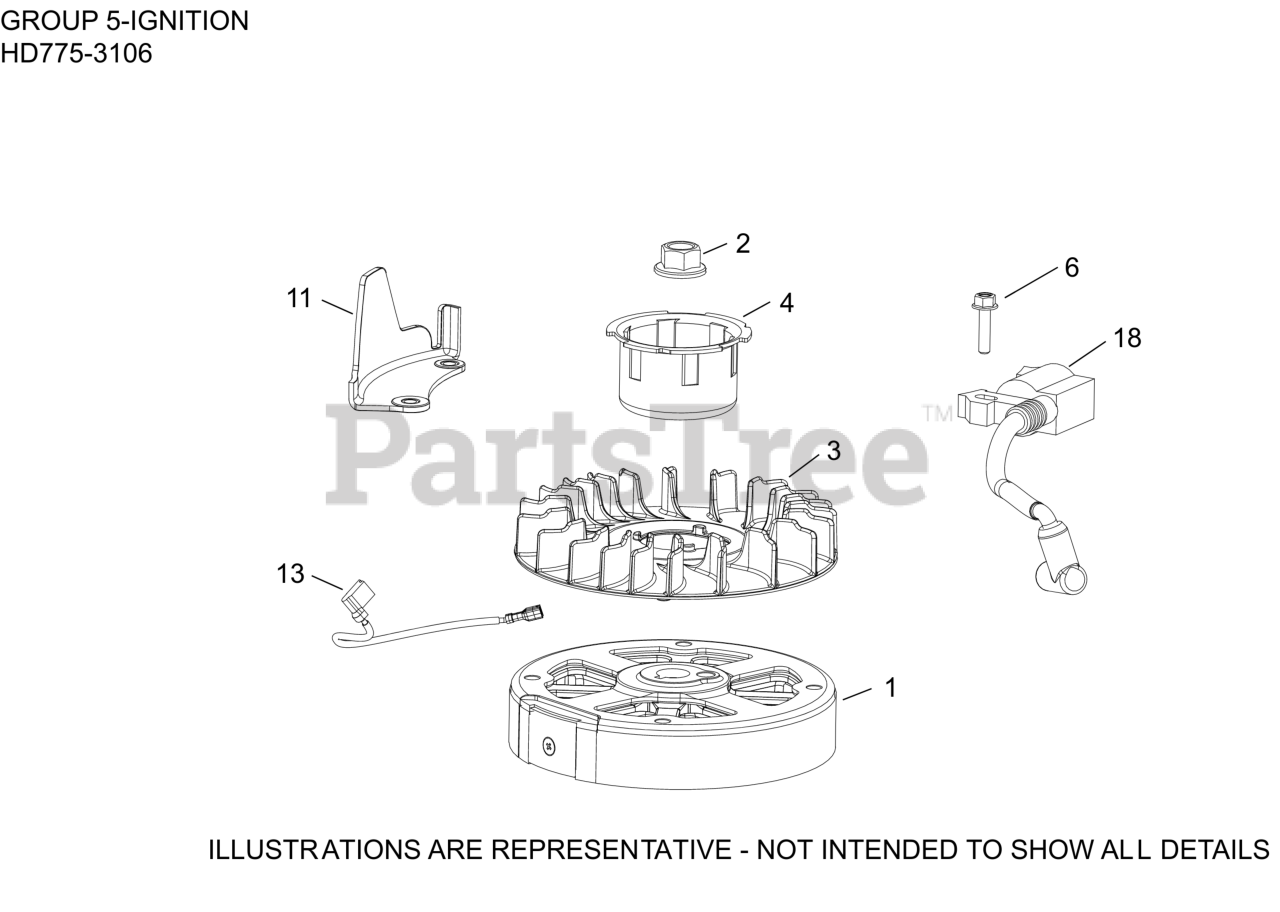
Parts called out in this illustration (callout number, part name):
1	FLYWHEEL ASSEMBLY
2	NUT, FLYWHEEL (W/SERRATIONS)
3	FAN, FLYWHEEL
4	CUP, DRIVE - (#1410905S)
6	SCREW, M6 X 25-(#25086436S)
11	GUARD, FINGER
18	MODULE IGNITION CAST IRON FLYWHEEL
